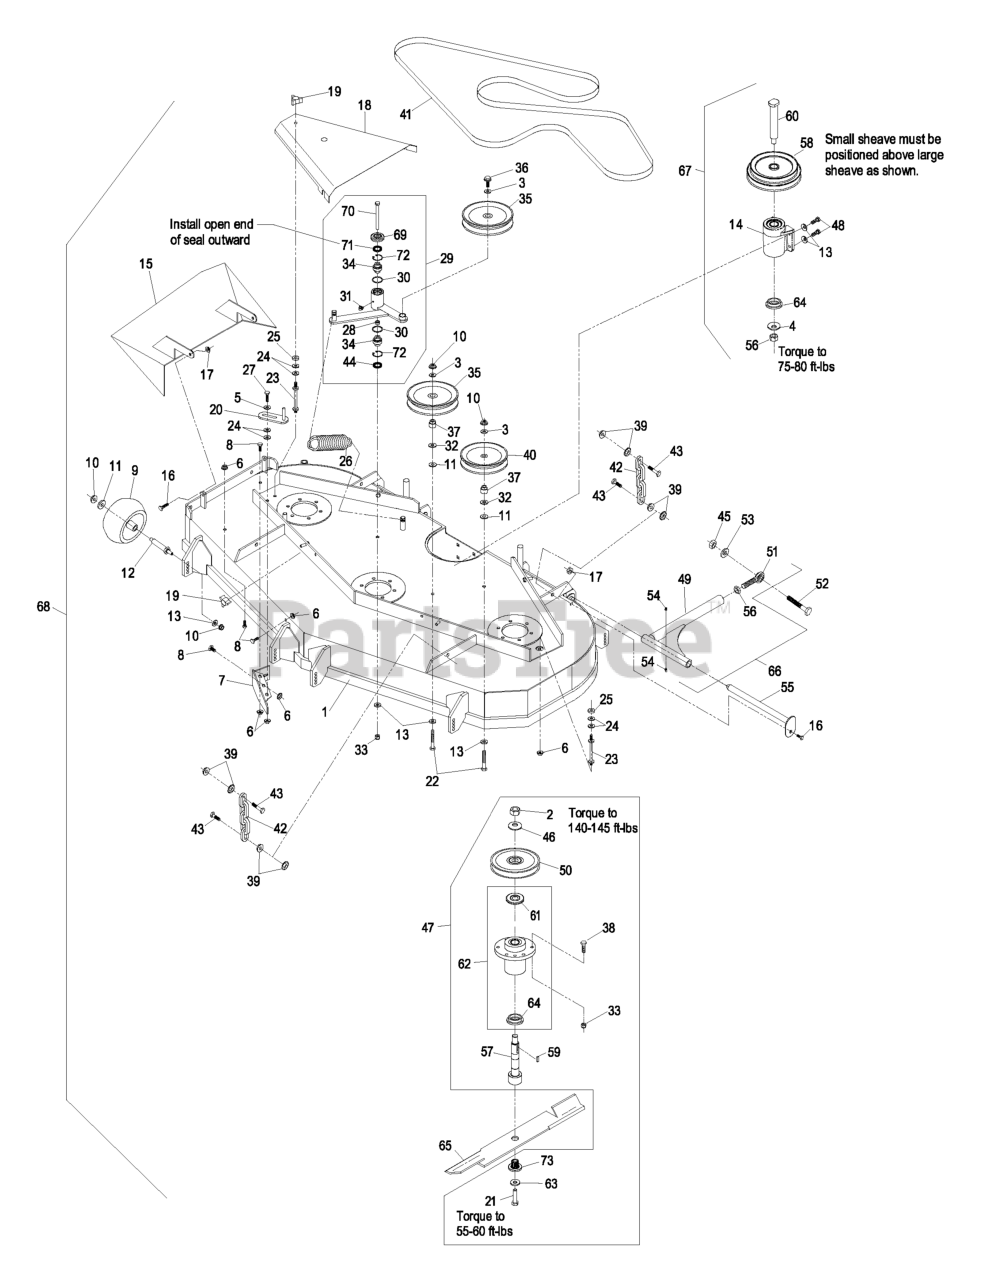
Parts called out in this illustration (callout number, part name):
1	ASM,DECK W/DECALS LZ604
2	NUT-HH
3	WASHER-FLAT
4	WASHER-SPRING
5	WASHER-SPRING
7	WLD,BAFFLE DISCHARGE
8	SCREW-HH
9	ROLLER-SCALP, ANTI
10	NUT-HHF, WHIZ
13	WASHER-BELLEVILLE
14	KIT, JACKSHAFT ASSY
15	WLD,CHUTE LZ604
16	SCREW-HH
17	NUT-LOCK, NI
18	SHIELD,BELT
19	KNOB-3 PRONG
20	GUIDE-BELT
21	SCREW-HH
22	BOLT-CARR
23	STUD-SHIELD, BELT (SHORT)
24	WASHER-FLAT
27	SCREW-HH
29	KIT,DECK IDLER LZ/XP
31	FITTING-GREASE, 90 DEG
32	WASHER-FLAT
33	NUT-LOCK, NI
34	BEARING-SPHERICAL
36	SCREW-HHF
37	BUSHING-IDLER
38	SCREW-HH
40	PULLEY-IDLER
41	BELT,BLADE DRIVE
42	CHAIN-LIFT, DECK
43	SCREW-HH
44	SEAL-LIP, DOUBLE
45	NUT-HEX
47	ASM, CUTTER HSG COMPLETE
48	SCREW-HH
50	SHEAVE,BLADE DRIVE 6.30
51	BALLJOINT-SPHERICAL
52	SCREW-HH
53	WASHER-LOCK
54	FITTING-GREASE
55	PIN-STRUT
56	NUT-HEX
57	KIT, SPLINED SPINDLE 103-
58	SHEAVE, JACKSHAFT DOUBLE
60	JACKSHAFT
61	GUARD-BEARING, TOP
62	KIT, CUTTER HOUSING
63	WASHER-SPRING
64	SPACER-GUARD, BOTTOM
66	STRUT ASM
67	KIT,JACKSHAFT 60/72-3750
68	Complete Deck Assy
69	GUARD-TOP
70	SCREW-HH
71	SEAL-LIP, SINGLE
72	RING-SNAP
73	BUSHING,SPLINED
